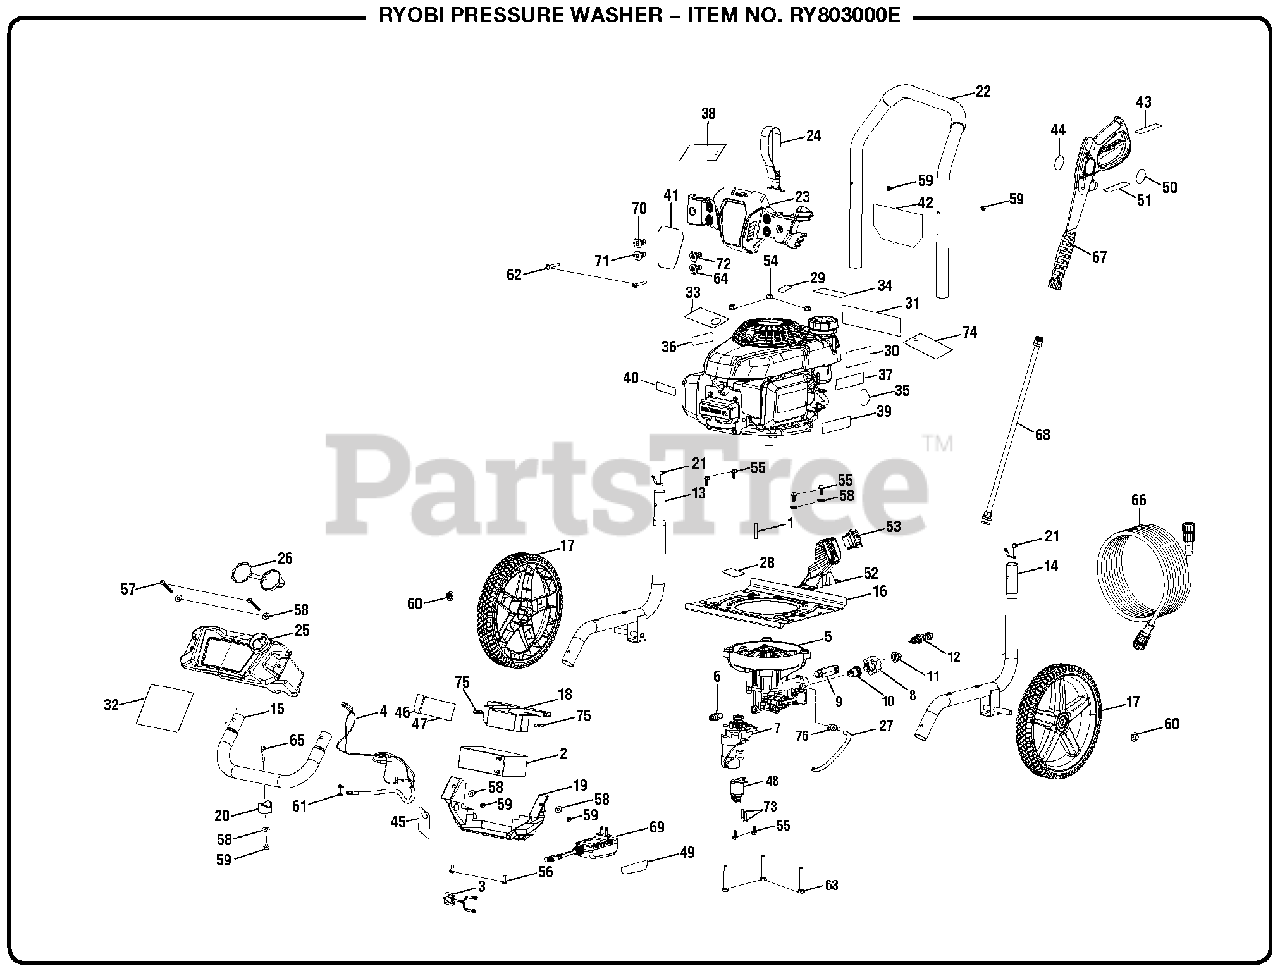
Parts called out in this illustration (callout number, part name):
1	Output Shaft Key
2	Battery (12V, 4.5Ah)
3	Battery and Charger Wire Harness
4	Wiring Harness (Battery to Relay)
5	Pump
6	Thermal Release Valve
7	E-Start Motor Assembly
8	Inlet Filter Adapter Insert
9	Outlet Tube
10	Inlet Filter Connector
11	Inlet Filter Screen
12	Unloader Valve Assembly
13	Left Frame Assembly
14	Right Frame Assembly
15	Front Frame Assembly
16	Engine Plate
17	Wheel
18	Battery Retainer
19	Battery Mount Bracket
21	Handle Spring Clip
22	Handle Assembly
23	Hose and Nozzle Holder Assembly
24	Hose Holder Strap
25	Soap Tank
26	Soap Tank Cap
27	Chemical Siphon Tube
28	Add Oil Label
29	Combustion Warning Label
30	Choke Label
31	Danger Label
32	Soap Tank Label
33	Oil Dipstick Hangtag
34	E85 Label
35	On/Off Label
36	Hot Surface
37	Inquiries Label
38	Nozzle Hangtag
39	EMC ICES-2/NMB-2 Label
40	Electric Start Label
41	Performance Label
42	Quick Start Label
43	Trigger Handle Warning Label (French/Spanish)
44	Spray Wand Logo Label
45	Battery Connection Hangtag
46	Battery Charging Port Label
47	Battery Charging Warnings Label
48	Relay Assembly
49	Battery Maintainer Label
50	Trigger Handle Warning Label (Eng)
51	Trigger Handle Specifications Label
52	Switch Bracket
53	Start Switch
54	Lock Nut (M8)
55	Bolt (M6 x 16 mm, Hex Flange Hd.)
56	Bolt (M6 x 16 mm, T-30 Torx Pan Hd.)
57	Bolt (M6 x 50 mm, T-30 Torx Pan Hd.)
58	Washer (1/4 in.)
59	Lock Nut (M6)
61	Screw (M4 x 12 mm, T20 Torx Pan Hd.)
62	Bolt (M6 x 42 mm, T30 Torx Pan Hd.)
63	Bolt (M8 x 60 mm, Hex Flange Hd.)
64	Soap Nozzle
65	Screw (M6 x 48 mm, T-30 Torx Hd.)
66	Hose (25 ft.)
67	Trigger Handle Assembly
68	Spray Wand
69	Battery Charger
70	0deg Nozzle
71	25deg Nozzle
72	40deg Nozzle
73	Bolt (M5 x 20 mm)
74	Danger Hangtag (French/English/Spanish)
75	Washers (M6)
76	Soap Injector Kit
